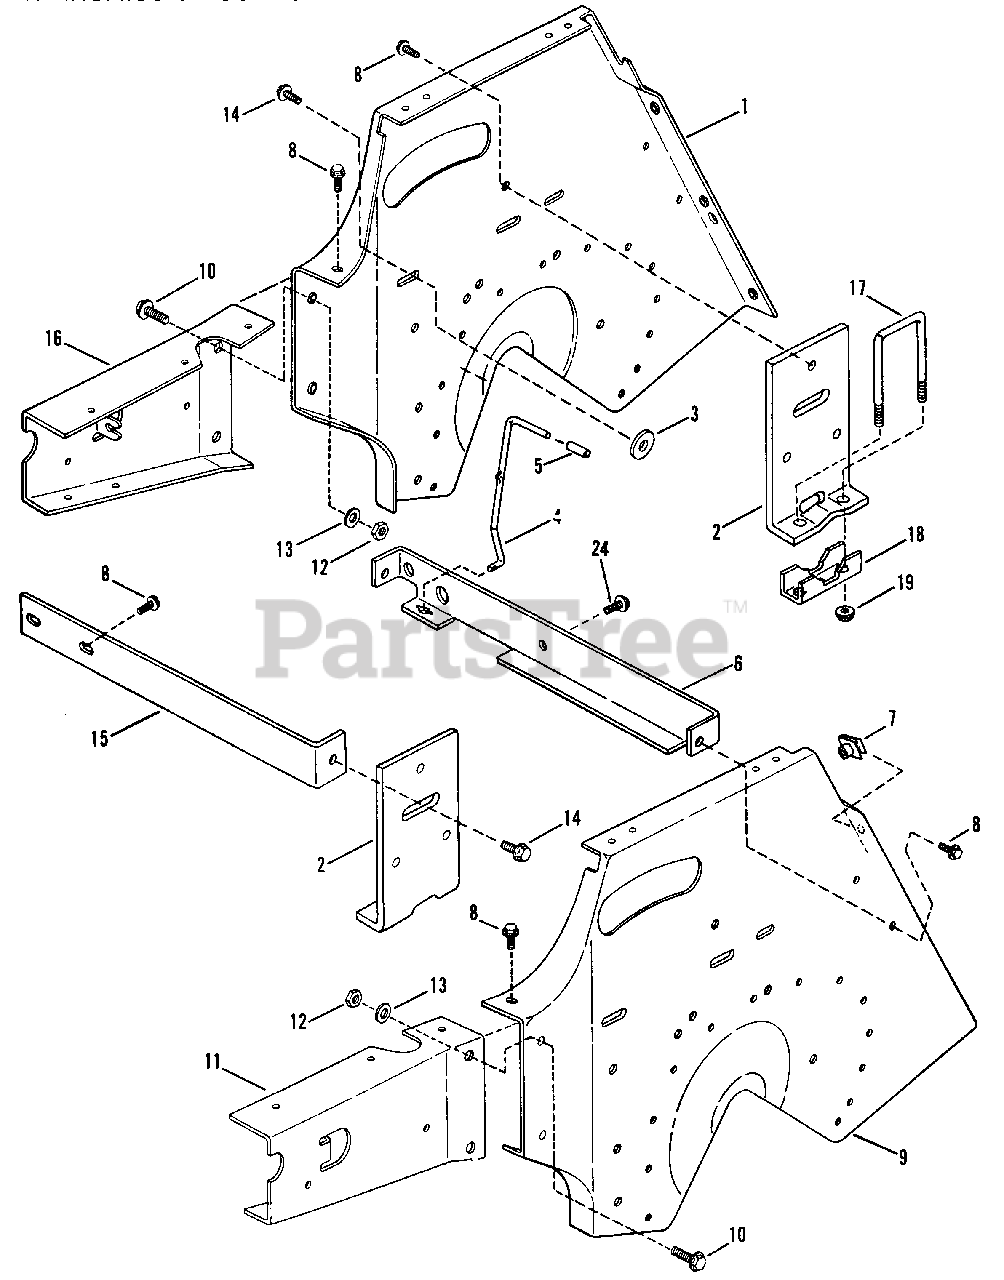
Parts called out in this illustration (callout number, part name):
1	TRANSMISSION SUPPORT, R.H. (No longer available)
2	BRACKET, Transmission Mount (No longer available)
3	WASHER .406 x 1.38 x .25
4	ROD, Release
5	CAP, Release Rod
6	BRACE, Torque
7	NUT, 5/16 Push-On
8	SCREW, 5/16-18 x 5/8" Self-Tapping
9	TRANSMISSION SUPPORT, L.H. (No longer available)
10	BOLT, 3/8-16 x 1" Hex Flange Lock
11	EXTENSION, Transmission Support, L.H. (No longer available)
12	NUT, 3/8-16 Center Lock
13	WASHER, 3/8 SAE
14	SCREW, 5/16-18 x 3/4" Self-Tapping
15	BRACE, Shift Bracket (No longer available)
16	EXTENSION, Transmission Support, R.H. (No longer available)
17	U-BOLT
18	SADDLE, U-Bolt
19	NUT, 5/16-18 Hex Flange Lock
24	SCREW, 5/16-18 X 7/8" Torx Self-Tap
